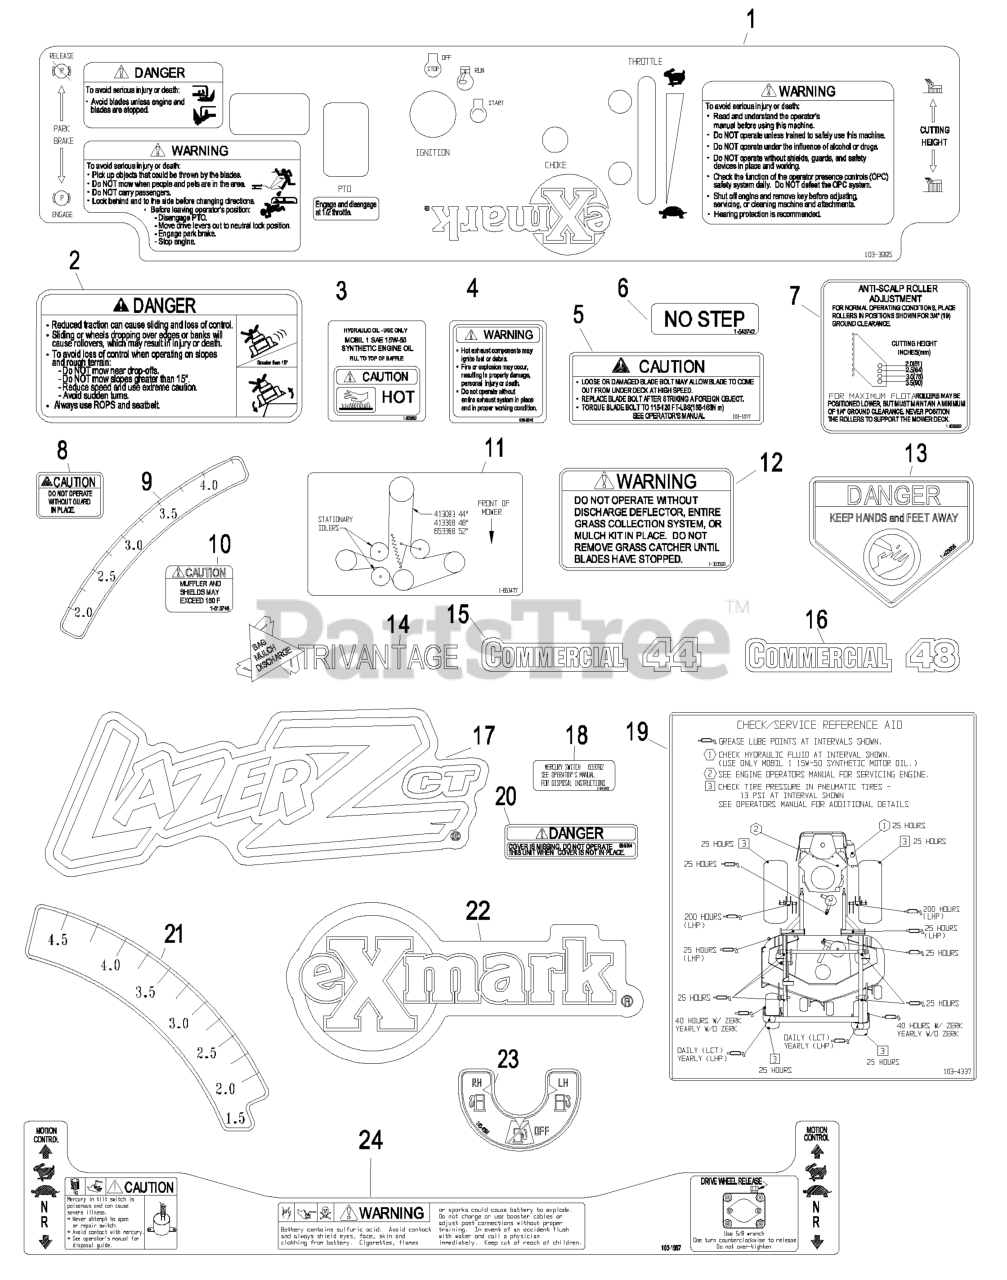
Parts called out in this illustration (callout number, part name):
1	DECAL,CONSOLE LHP
2	DECAL-DANGER, SLOPE
4	DECAL-EXHAUST
5	DECAL,BOLT TORQUE
6	DECAL,NO STEP
7	DECAL,ANTISCALP
8	DECAL-GUARD
9	DECAL-DECK HEIGHT, INNER
12	DECAL-WARNING, DISCHARGE
13	DECAL-DANGER
15	DECAL,COMMERCIAL 44
16	DECAL,COMMERCIAL 48
17	DECAL,LCT MODEL
18	DECAL-SWITCH, MERCURY
20	DECAL-COVER, MISSING
21	DECAL-DECK HEIGHT, OUTER
22	DECAL,EXMARK LOGO
23	DECAL-VALVE, FUEL
